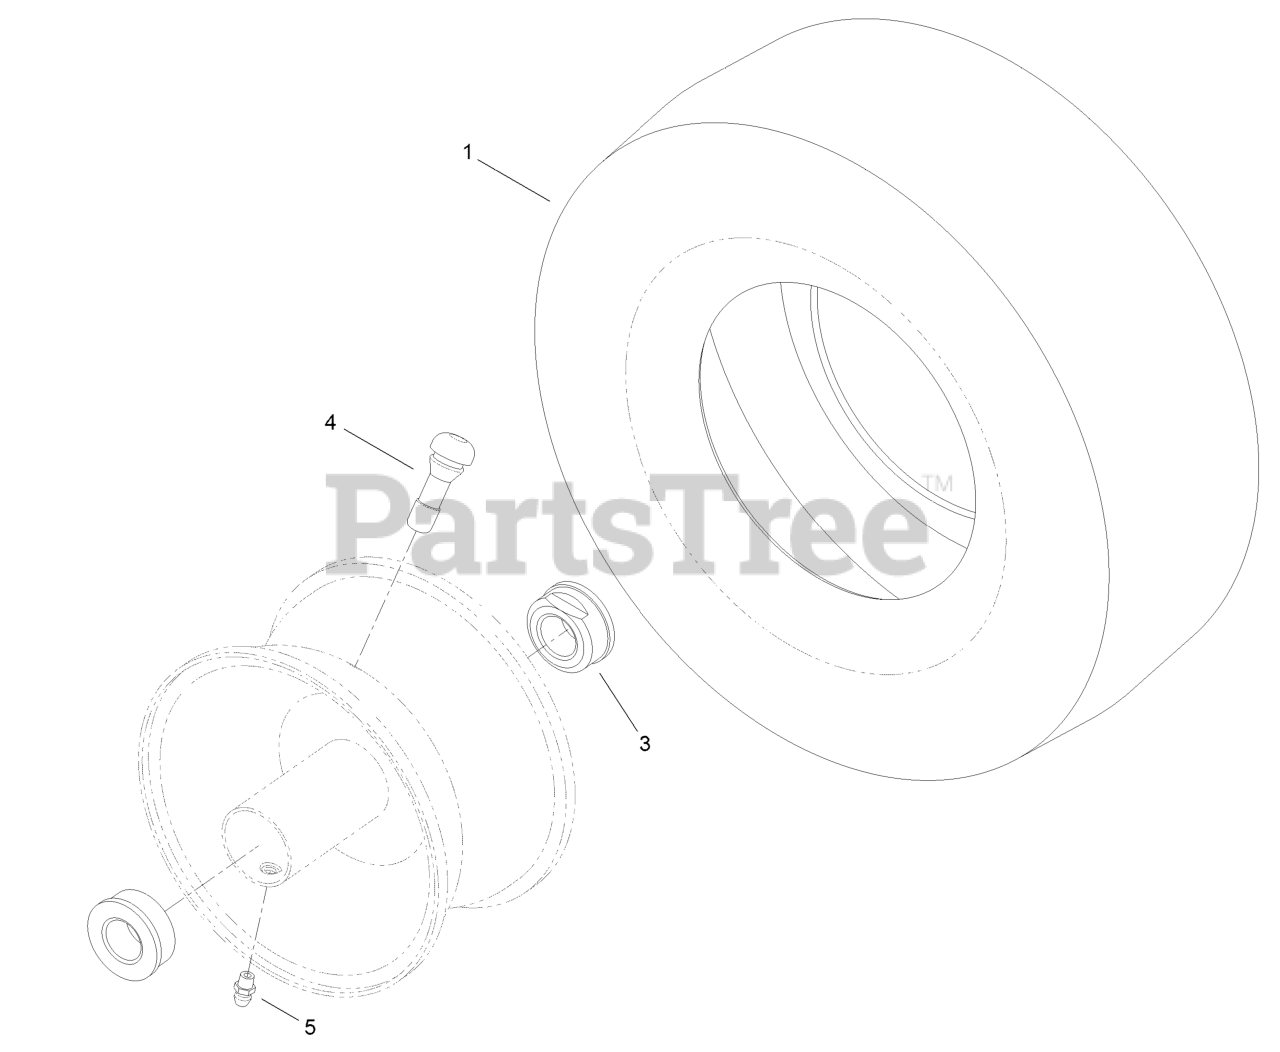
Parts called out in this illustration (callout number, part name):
1	TIRE-13 INCH
3	BUSHING-FLANGE
4	Stem-Valve
5	FITTING-GREASE
